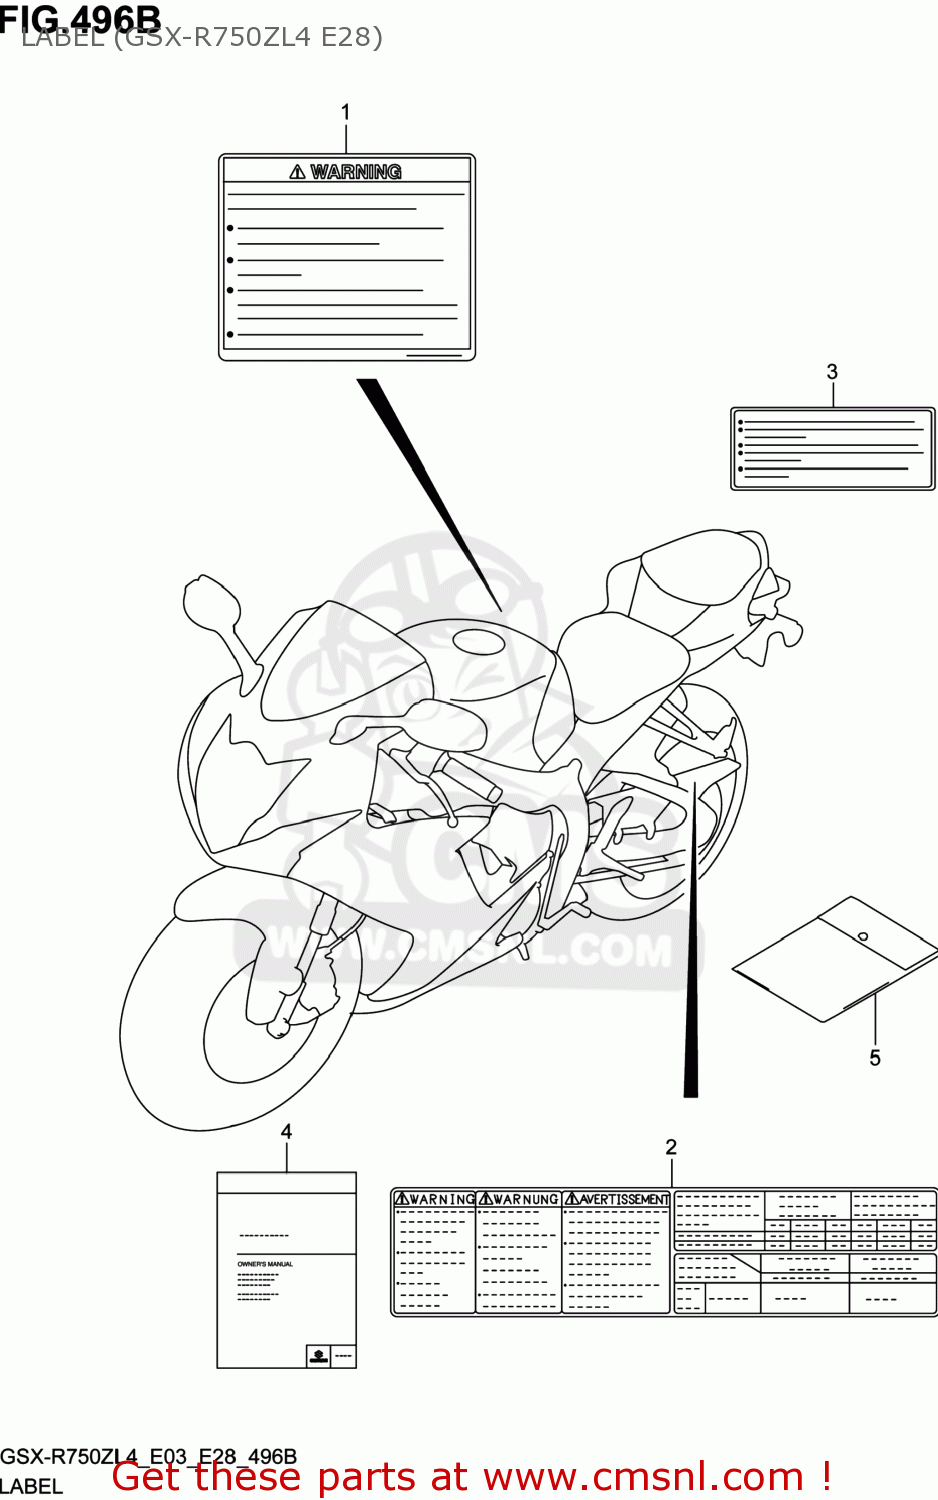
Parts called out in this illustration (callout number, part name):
1	LABEL,GENERAL WARNING
2	LABEL,TIRE INFORMATION
3	LABEL,FUEL INFORMATION
4	MANUAL,OWNER'S
5	BAG,OWNER'S MANUAL
